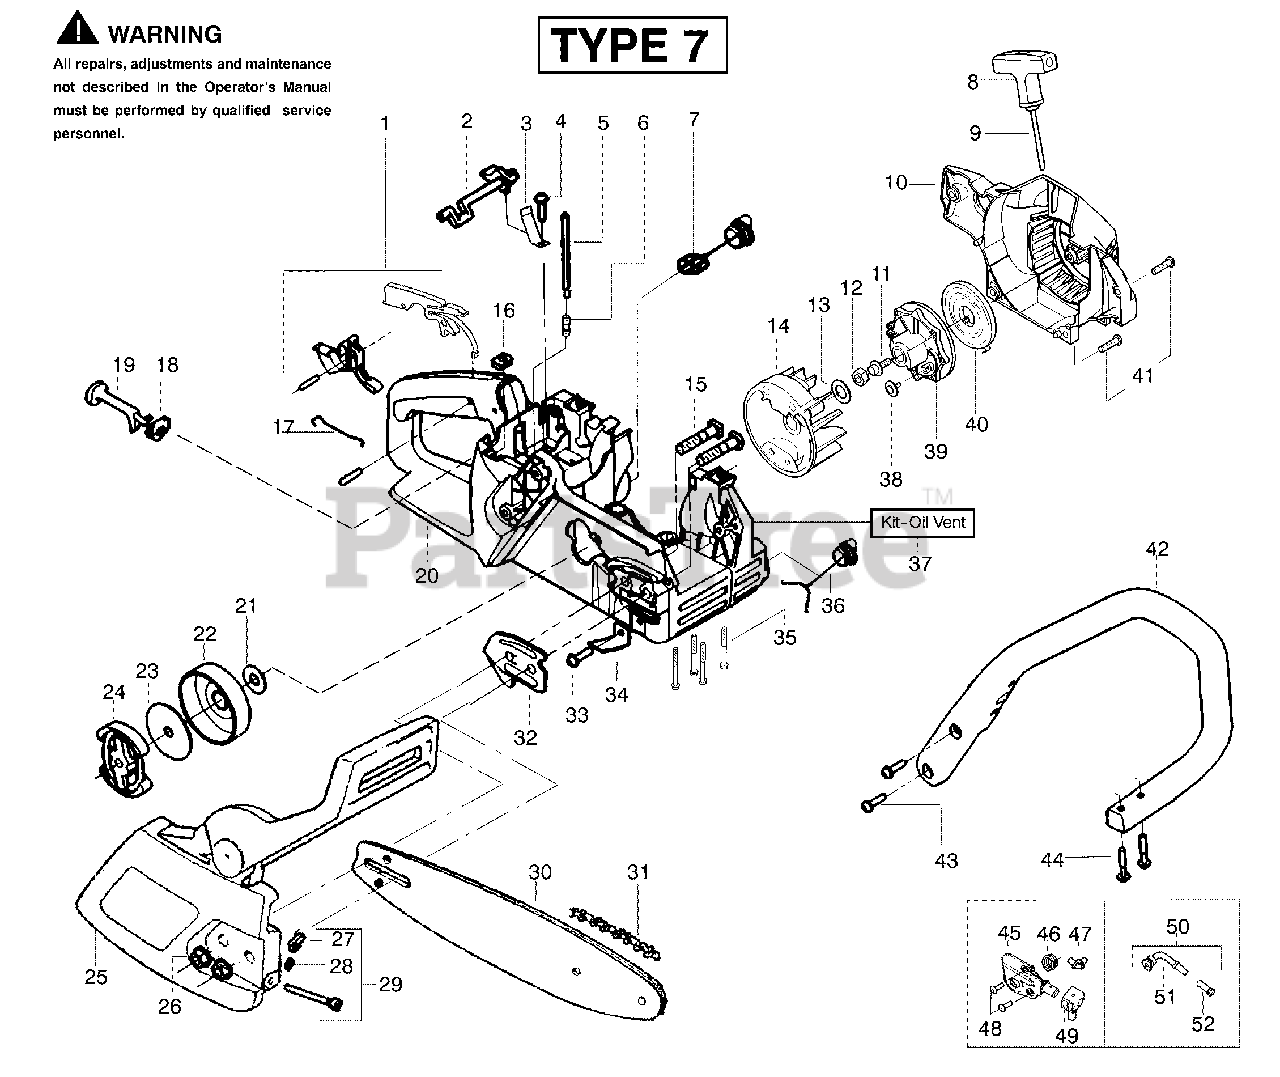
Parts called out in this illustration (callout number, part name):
1	Kit-Trigger & Lockout
2	Lever-Switch
3	Spring-Switch
5	Kit-Fuel Line (Large)
7	Assy-Fuel Cap
8	Handle-Starter
9	Kit-Rope
10	Housing-Fan
12	Nut-Flywheel
13	Washer-Flywheel
14	Assy-Flywheel
15	Bolt-Bar Mounting
16	Nut-Speed
17	Wire-Throttle
18	Grommet-Choke Knob
19	Lever-Choke
20	Assy-Chassis Green
20	Assy-Chassis Black
21	Washer - Thrust
22	Assy-Drum W/brg.
23	Washer-Clutch
24	Assy. - Clutch
25	Assy-Chain Brake
26	Nut-Bar Mounting
27	Pin-Bar Adjust
28	Retainer-Bar Adjust
29	Kit-Bar Adjust
30	Bar- 14"
31	Chain- 14"
32	Plate-Bar Mounting
34	Chain Catcher
36	Assy-Oil Cap
37	Kit-Oil Vent
39	Pulley-Starter
40	Spring-Starter
42	Handle-Front
45	Kit-Oil Pump
46	Gear-Worm Spring
47	Elbow-Oil Pickup
49	Seal Block
50	Assy-Oil-Pickup
51	Pickup-Oiler
52	Filter-Oil
